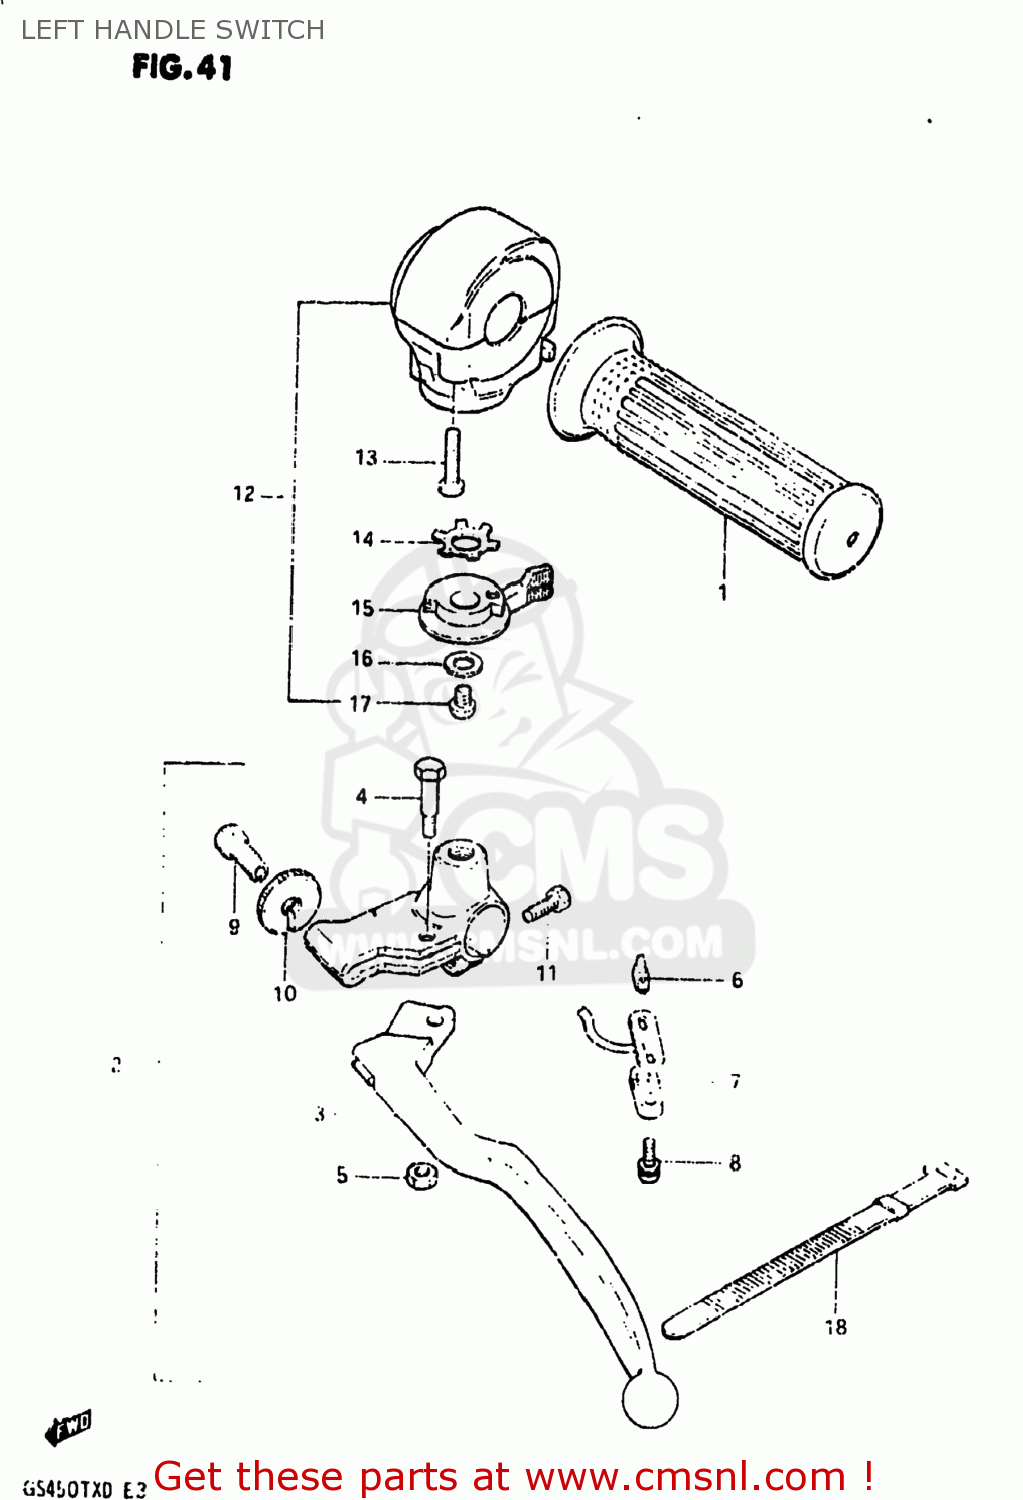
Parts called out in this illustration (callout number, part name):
1	GRIP,LEFT
2	LEVER ASSEMBLY
3	LEVER,CLUTCH
4	BOLT,LEVER
5	NUT 6MM
6	CONTACT,SWITCH
7	COVER,FR BK TERMINAL BASE
8	SCREW
9	ADJUSTER,CABLE
10	NUT,CABLE ADJUSTER
11	BOLT,CLUTCH LEVER HOLDER
12	SWITCH ASSEMBLY,HANDLE,LEFT
13	SCREW
14	WASHER
15	LEVER,STARTER
16	WASHER 6MM
17	SCREW
18	CLAMP(L:120)
